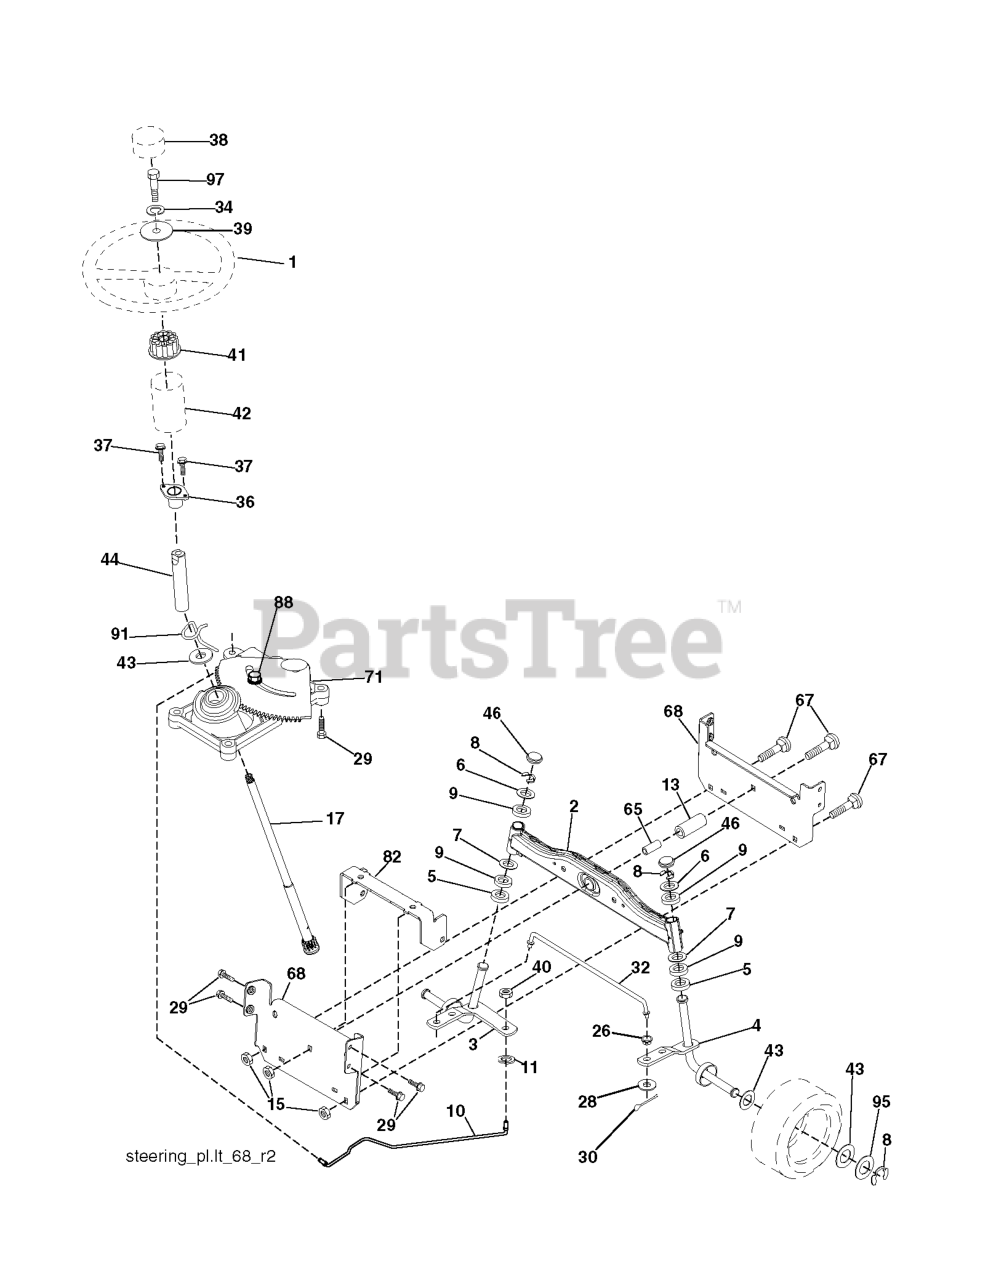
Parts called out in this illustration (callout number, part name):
1	WHEEL.STEERING.OPP.BLACK
2	AXLE.HALF.ASM.WELDED
3	SPINDLE.ASM.LH.15"TIRES
4	SPINDLE.ASM.RH.15"TIRES
5	THRUST WASHER
9	BRNG T
10	DRAGLINK.15".TIRES.2001
11	WASHER, LOCK 3/8
13	TUBE, PIVOT AXLE
15	NUT
17	SHAFT STEERING SPLINE
26	BUSHING.DRAGLINK (2 2)
28	WASHER
29	SCREW, 3/8-16X3/4
30	COTTER PIN
32	ROD.TIE.WIRE.FORM
34	WASHER.LOCK.HVY.HLCL.SPR.5/16
36	BUSHING, STEERING
37	SCREW.TT.#10-32X.5.3/8.FLANGE
38	CAP.WHEEL.STEER.OPP.BLK
39	WASHER.11/32
40	NUT CROWNLOCK 3/8-24
41	ADAPTER, WHEEL STNG..
42	BOOT.STEERING.SHAFT.BLACK
44	SHAFT.EXTEN.STRG.SPLINE
46	CAP.SPINDLE.BLACK
65	SPACER BRACE AXLE
67	BOLT CARRIAGE
68	BRACE.AXLE.15"TIRES
71	STEERING ASM
82	BRACKET.SUSP.CHASSIS.FRONT.15
88	BOLT, SHOULDER 7/16-20
91	CLIP.STEERING
95	WASHER.HARDENED
